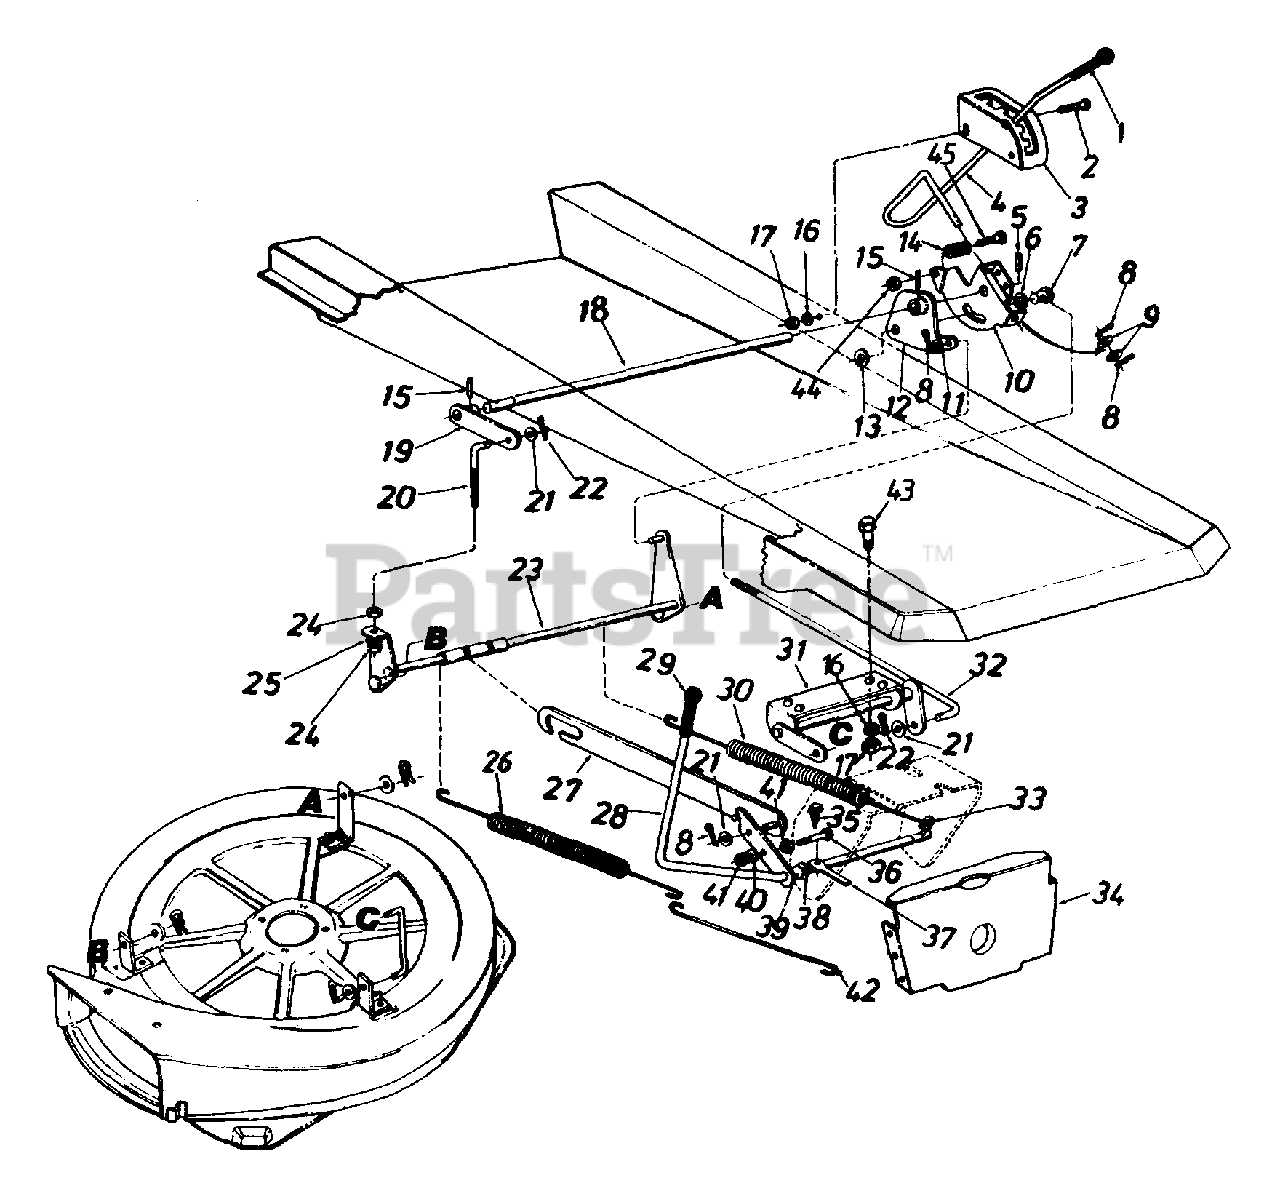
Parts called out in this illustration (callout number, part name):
2	Truss Mach. Scr. 5/16 - 18 x .75" Lg.
5	Spring Pin Spir. 3/16" Dia. x 1.50" Lg.
6	FL-Wash. .385" I.D. x .87" O.D.
7	Adj. Ferrule Deck Lift Handle
8	Cotter Pin 1/8" Dia. x 1.0"
9	FL-Wash. .531" I.D. x .930" O.D.
12	Deck Lift Brkt. Ass'y. - L.H.
13	FL-Wash. .635" I.D. x 1.04" O.D.
14	Compression Spring .5" Dia. x .9" Lg.
15	Spring Pin Spir. 1/4" Dia. x 1.50" Lg.
16	L-Wash. 5/16" I.D.
17	Hex Nut 5/16 - 18 Thd.
18	Rear Hgt. Adj. Shaft
19	Deck Lift Brkt. Ass'y. - R.H.
20	Deck Adj. Scr. 3/8 - 16 Thd.
21	FL-Wash. .385" I.D. x .87" O.D.
22	Intern. Cotter Pin 1/2" Dia.
23	Deck Link Ass'y.- Rear
24	Hex Nut 3/8 - 16 Thd.
25	L-Wash. 3/8" I.D.
26	Extension Spring 13.25" Lg.
30	Extension Spring 13.25" Lg.
31	Deck Lift Ass'y. - Front
32	Deck Lift Connecting Rod
33	Clevis Pin Special .250" Dia.
36	Hex Bolt 5/16 - 18 x 1.50" Lg. (Grade 5)
37	Switch Actuator
38	FL-Wash. .531" I.D. x .930" O.D.
39	Spacer .511" I.D. x .70" O.D. x .38" Lg.
40	L-Wash. 5/16" I.D.
41	Hex Nut 5/16 - 18 Thd.
42	Spring Hook
43	Hex Bolt 5/16 - 18 x .75" Lg.
44	Hex Cent. L-Nut 1/4 - 20 Thd.
45	Hex Bolt 1/4 - 20 x 1.25" Lg.
